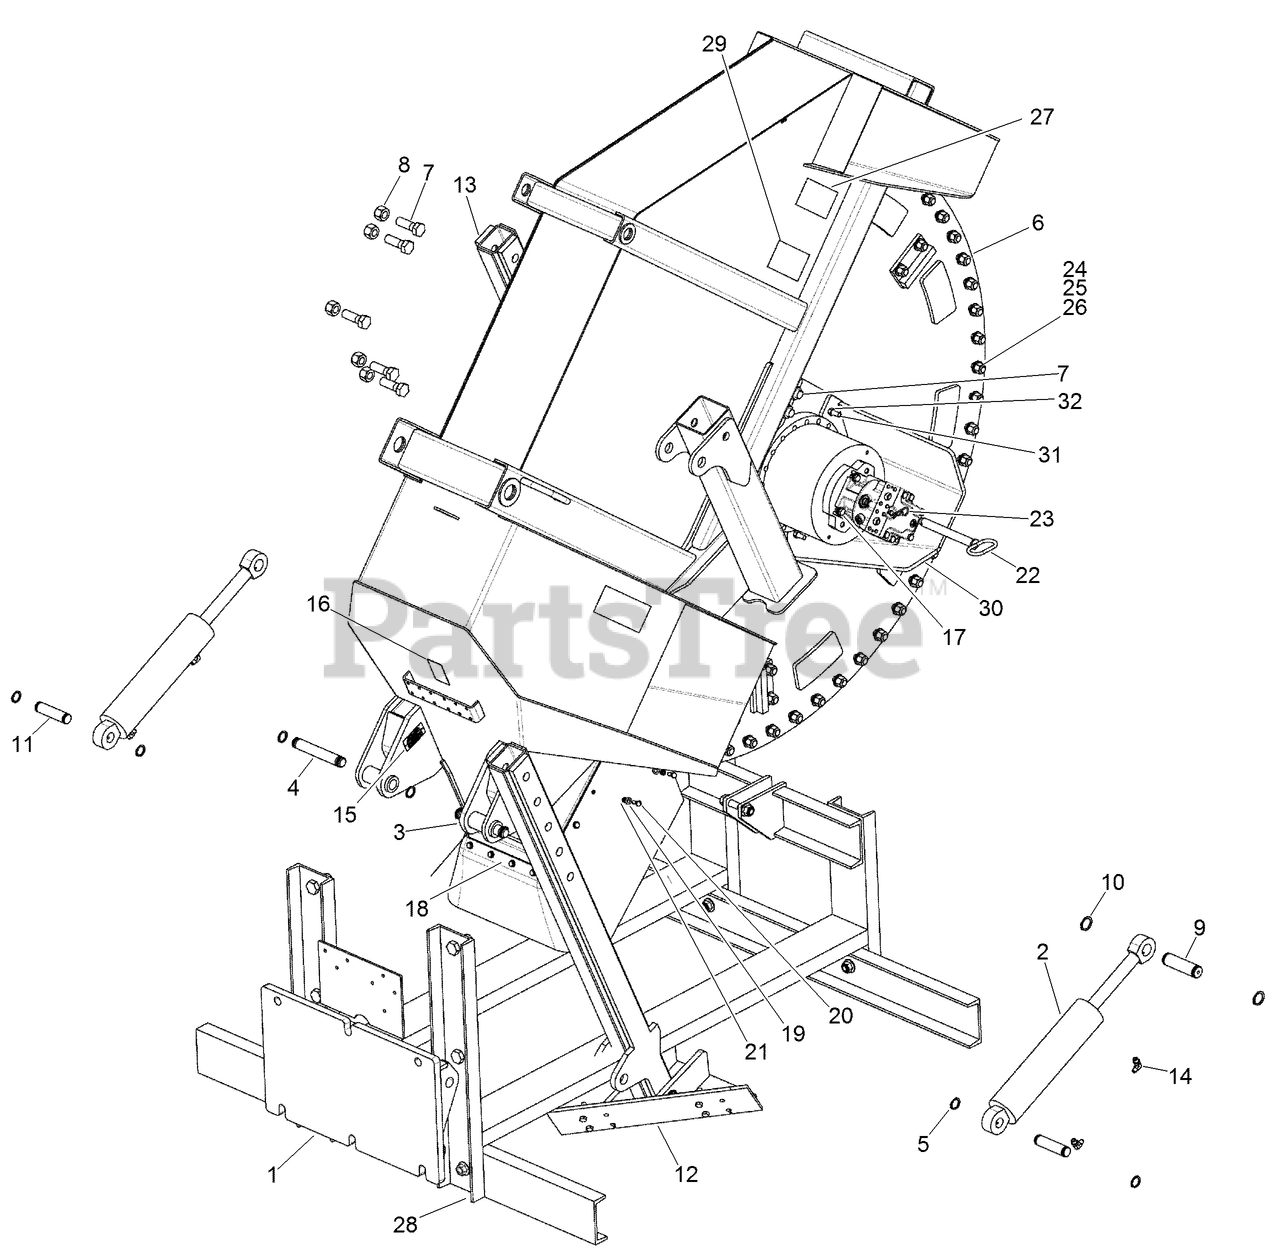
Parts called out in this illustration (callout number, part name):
1	WELDMENT - Rock Wheel Mount
2	CYLINDER ASSEMBLY - 89 (3-1/2) ID x 290 mm (11-13/32 inch) Stroke, Plow Lift
3	FRAME WELDMENT - Rock Wheel
4	PIN-STABILIZER CYLINDER TO ARM
5	RING-RETAINING
6	WHEEL ASSEMBLY - Motor/Disc/Hardware
9	PIN-PIVOT
11	PIN-pivot, swing tower, small
12	ASSEMBLY - Stabilizer, LH
13	ASSEMBLY - Stabilizer, RH
14	ELBOW-90 DEG (ADJUSTABLE 37 DEG)
15	PLATE - Serial Number
16	DECAL - Warning, General Operation
17	WASHER-FLAT
18	SKIRT - Rock Wheel
19	WASHER-0.406 x 0.812 x 0.065 in CST ZND
20	BOLT-hex, 3/8 NC x 1-1/2 inch
21	NUT
22	PIN - Mounting
23	PIN-Hair
25	BOLT - Hex Hd .75 x 3.25 GR8 ZND
26	NUT-Prev Trq 3/4 GRC CAD Direct
27	DECAL - Wheel Hazard
28	STAND - Rock Saw
29	DECAL - Danger, Tren Entangle Hazard
30	WELDMENT - Motor Guard
32	NUT-LOCK, HEX
